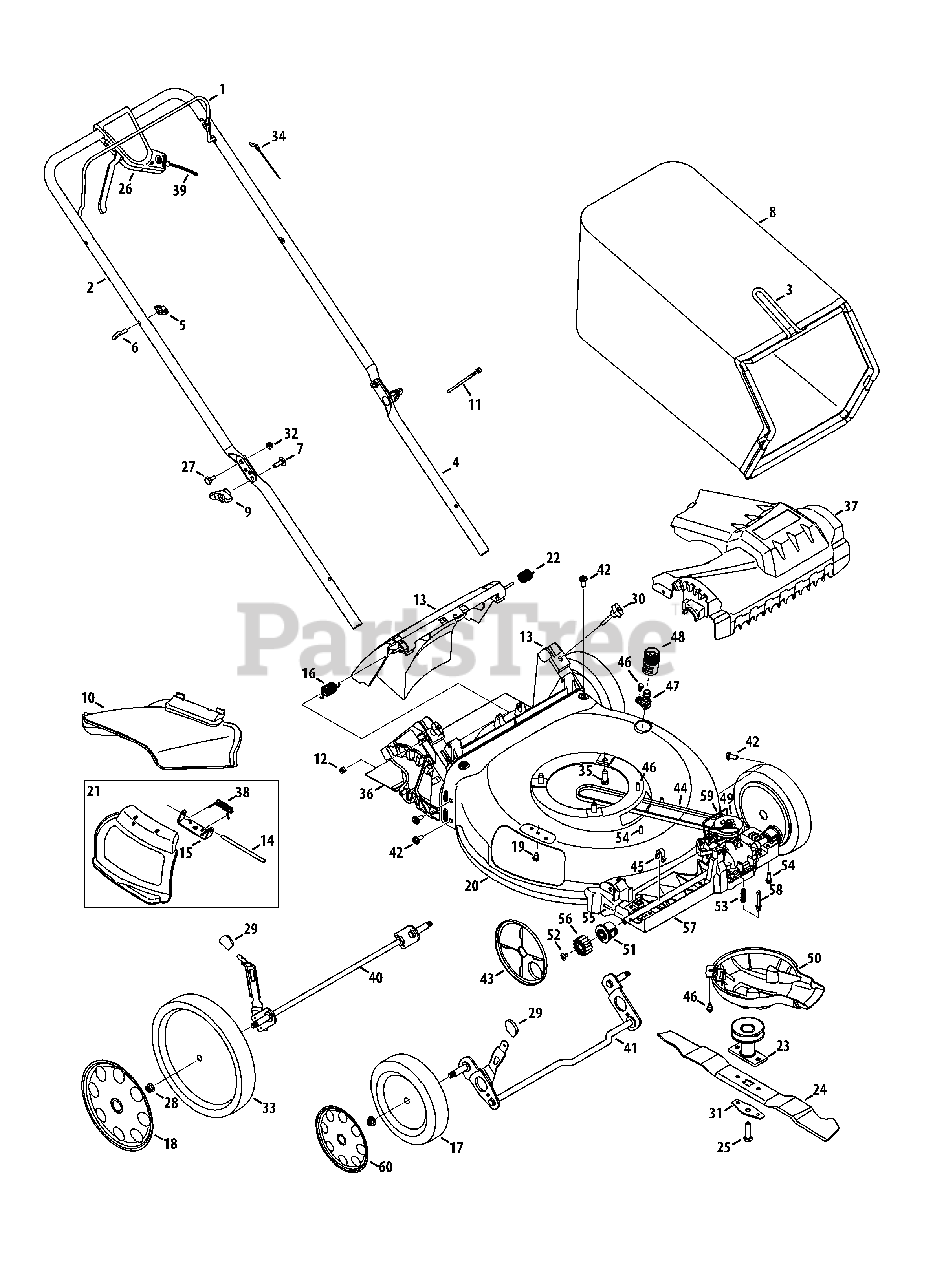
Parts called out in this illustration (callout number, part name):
1	Blade Control
2	Upper Handle
3	Grass Catcher Frame
4	Lower Handle
6	Rope Guide
7	Carriage Screw ,5/16-18
8	Grass Bag
10	Side Chute
11	Cable Tie
12	Nut, Sq., 1/4-20
13	Rear Discharge Door Assembly
15	Chute Deflector Bracket
16	Torsion Spring - RH
17	Front Wheel
19	Screw, 1/4-20 x .500
20	Deck , 21"
21	Hinged Mulch Plug Assembly
22	Torsion Spring - LH
23	Blade Adapter Assembly
24	Mulching Blade
25	Screw , 3/8-24 x 1.50
26	Control Lever Assembly
27	Sldr. Screw, .375 x .126 x 1/4-20
28	Flange Lock Nut, 3/8-16
29	Adjustment Lever Knob
30	Wing Nut
31	Blade Bell Support
32	Nut, Flange Lock, 1/4-20
33	Rear Wheel
34	Control Cable (Honda)
35	TT Sems Screw, 3/8-16 x 1.0
36	Trail Shield
37	Front Cover
38	Torsion Spring
39	Variable Speed Cable
40	Rear Axle Assembly
41	Front Axle Assembly
42	Screw, 5/16-14 x .750
43	Wheel Dust Cover
45	Front Axle Clip
46	Scr., Shldr., 1/4-20 x .50
47	Water Nozzle
48	Water Nozzle Adapter
49	Transmission Assembly
50	Engine Baffle
51	Bearing Assembly
52	Screw, 1/4-20 x .390
53	Compression Spring
54	Screw, 1/4-15 x .750
56	Spur Gear, 14T - RH
56	Spur Gear, 14T - LH
57	Lower Tray
58	Spring Body
59	Transmission Wire
60	Hubcap, 8"
